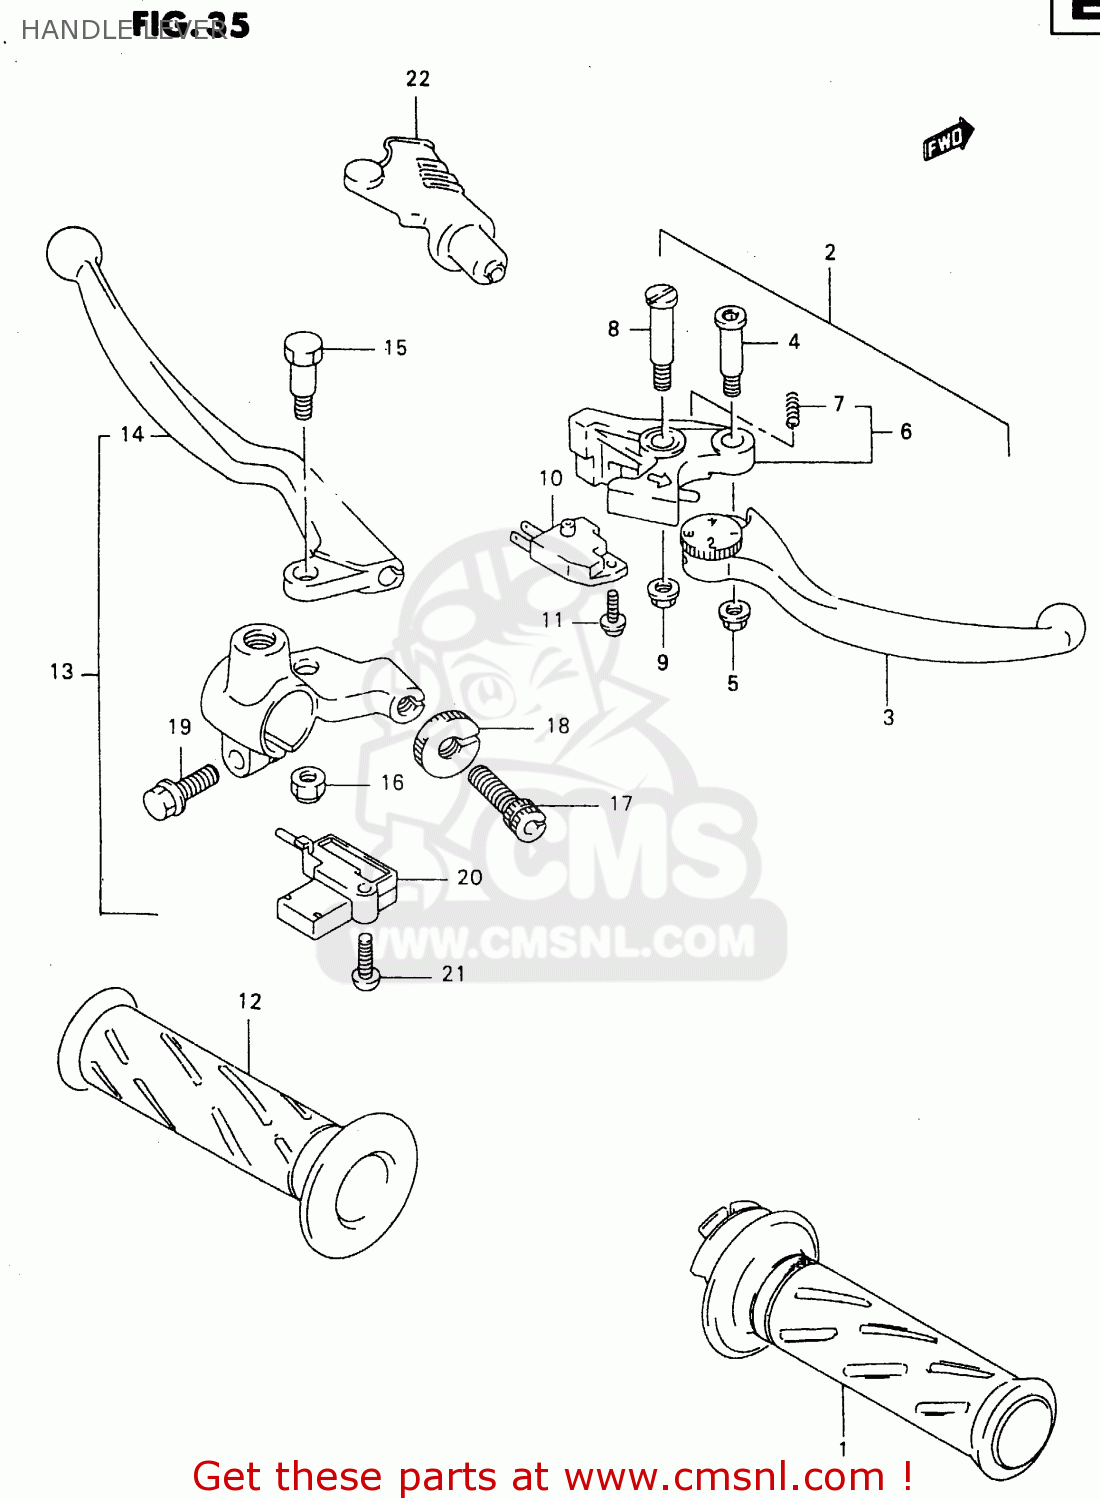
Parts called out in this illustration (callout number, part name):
1	GRIP,THROTTLE
2	LEVER ASSY,BRAKE
3	LEVER,ADJUST
4	BOLT,LEVER
5	NUT
6	KNOCKER
7	SPRING
8	BOLT,LEVER PIVOT
9	NUT
10	SWITCH ASSEMBLY,STOP
11	SCREW
12	GRIP,LEFT
13	LEVER ASSY,CLUTCH
14	LEVER,CLUTCH
15	BOLT,LEVER SET
16	NUT
17	ADJUSTER,WIRE
18	NUT,LOCK
19	SCREW
20	SWITCH,CLUTCH
21	SCREW
22	COVER,CLUTCH LEVER
